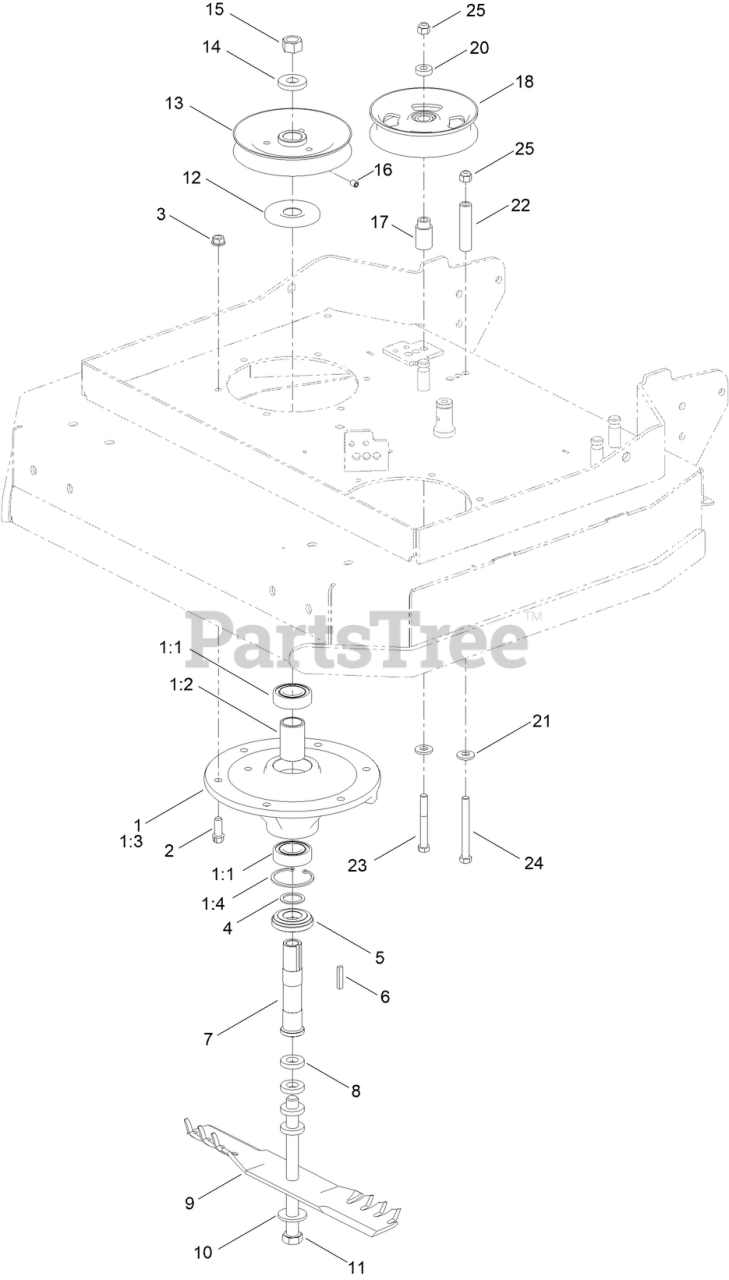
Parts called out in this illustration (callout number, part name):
1	SPINDLE HOUSING ASM
1:1	BEARING-BALL, 1 INCH
1:2	SPACER-BEARING
1:3	HOUSING-SPINDLE
1:4	RING-SNAP
2	SCREW-TAPTITE
3	NUT-HHF, WHIZ
4	WASHER-SPACER
5	SPACER-GUARD, BOTTOM
7	TUBE-SPINDLE, SHORT
8	SPACER
9	BLADE-ATOMIC
10	WASHER-SPRING
11	SCREW-CAP, HH
12	GUARD-BEARING, TOP
13	SHEAVE
14	WASHER-RETAINER, SHEAVE
15	NUT-HEX
16	SCREW-SET
17	BUSHING-IDLER
18	PULLEY-IDLER,FLAT
20	SPACER
21	WASHER-BELLEVILLE
22	SPACER
23	SCREW-HH
24	SCREW-HH
25	NUT-LOCK, NI
